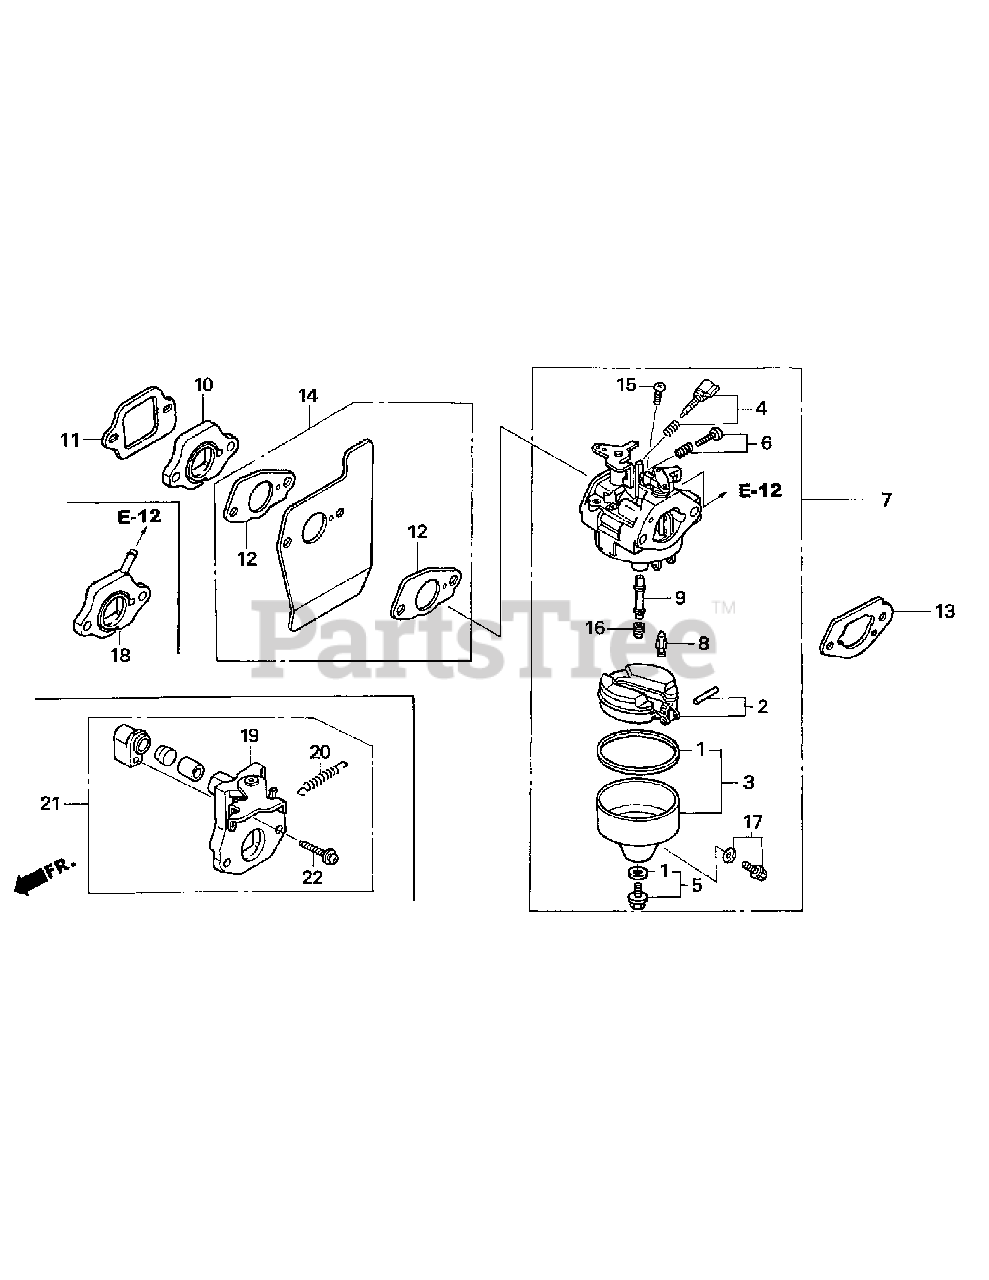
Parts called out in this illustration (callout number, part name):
1	GASKET SET
3	CHAMBER SET, FLOAT (CARBURETOR NO.)
5	SCREW SET B
7	CARBURETOR ASSY. (BB65A A)
8	VALVE, FLOAT (CARBURETOR NO.)
9	NOZZLE, MAIN
10	INSULATOR, CARBURETOR
11	GASKET, INSULATOR
12	GASKET, CARBURETOR
13	GASKET, CARBURETOR (CHOKE SIDE)
14	GUIDE, AIR
15	SCREW, PAN (5X6)
16	JET, MAIN (#60) (CARBURETOR NO. )
17	SCREW SET, DRAIN (CARBURETOR NO.)
